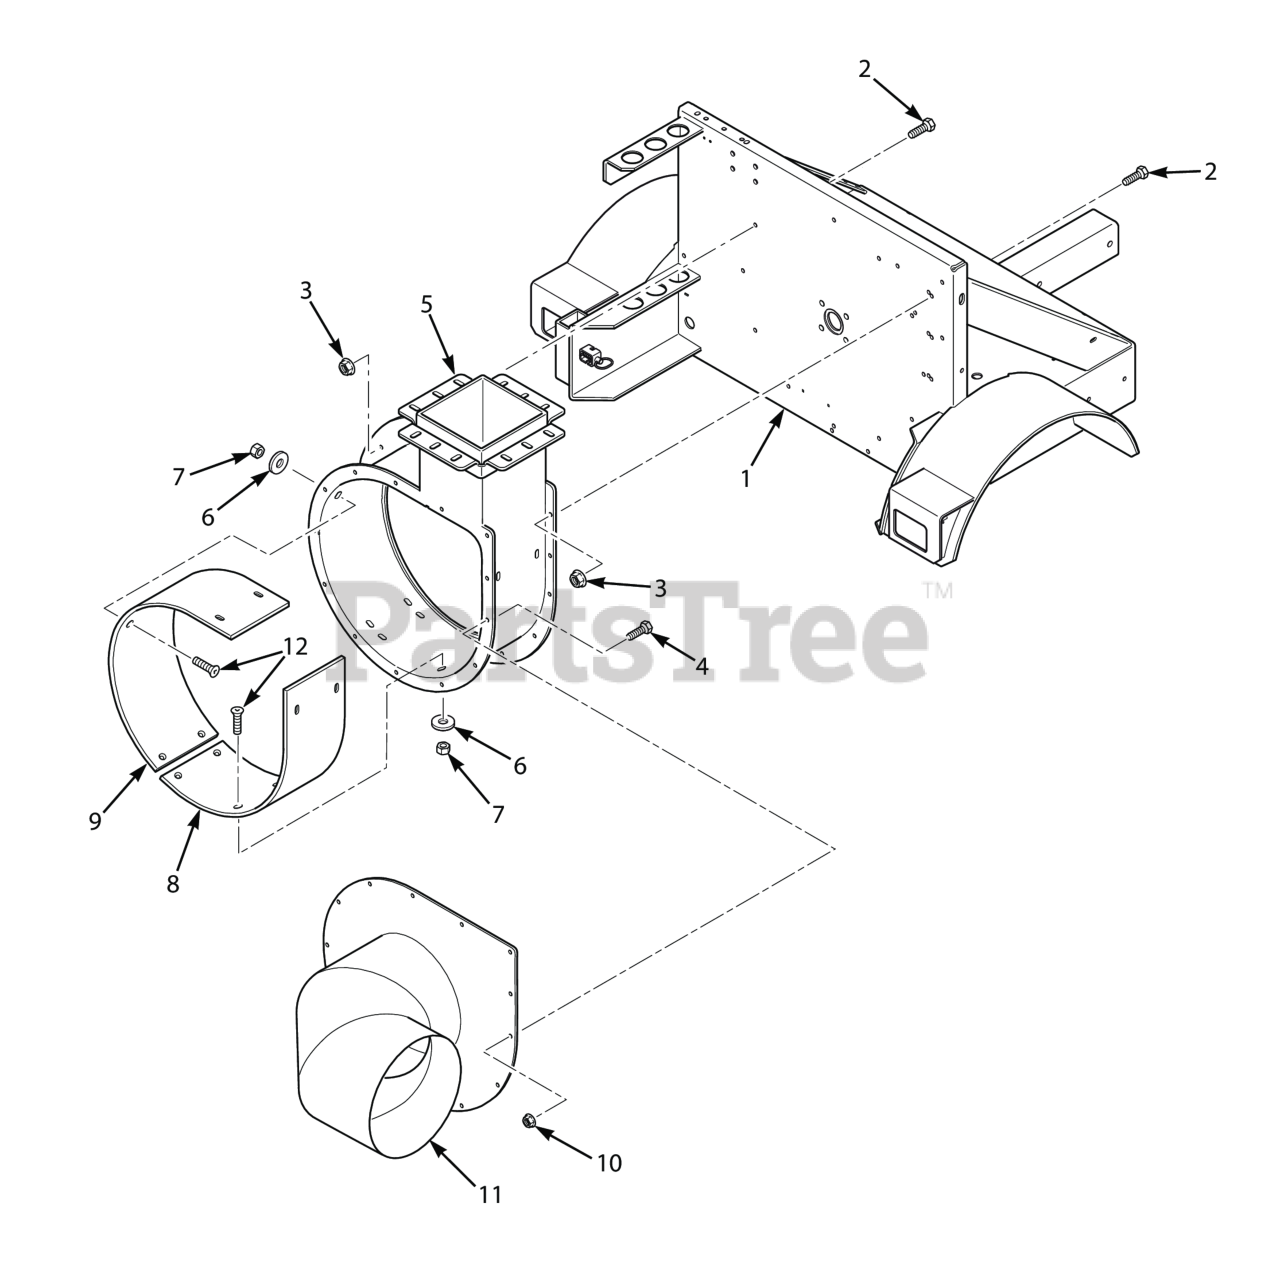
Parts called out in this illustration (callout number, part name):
1	Base and Frame w/Decals
2	Bolt, Hex Head 7/16-14 x 3/4"
3	HEX NUT, 7/16-14 SERRATED FLANGE
4	Bolt, Hex Head Serrated Flange 3/8-16 x 3/4"
5	Impeller Housing Assembly- TLB25 (incl. # 6, 7, 8, 9, 12)
6	Flat Washer, 1/2 (.562 x 1.375 x .109)
7	HEX LOCKNUT, ELASTIC STOP, 1/2-13
8	Wear Band, Long - TL25
9	Wear Band, Short - TL25
10	NUT, 3/8-16 SERRATED FLANGE HEX HEAD
11	Intake Elbow, TLB25
12	Capscrew, 1/2-13 x 1-1/2"
